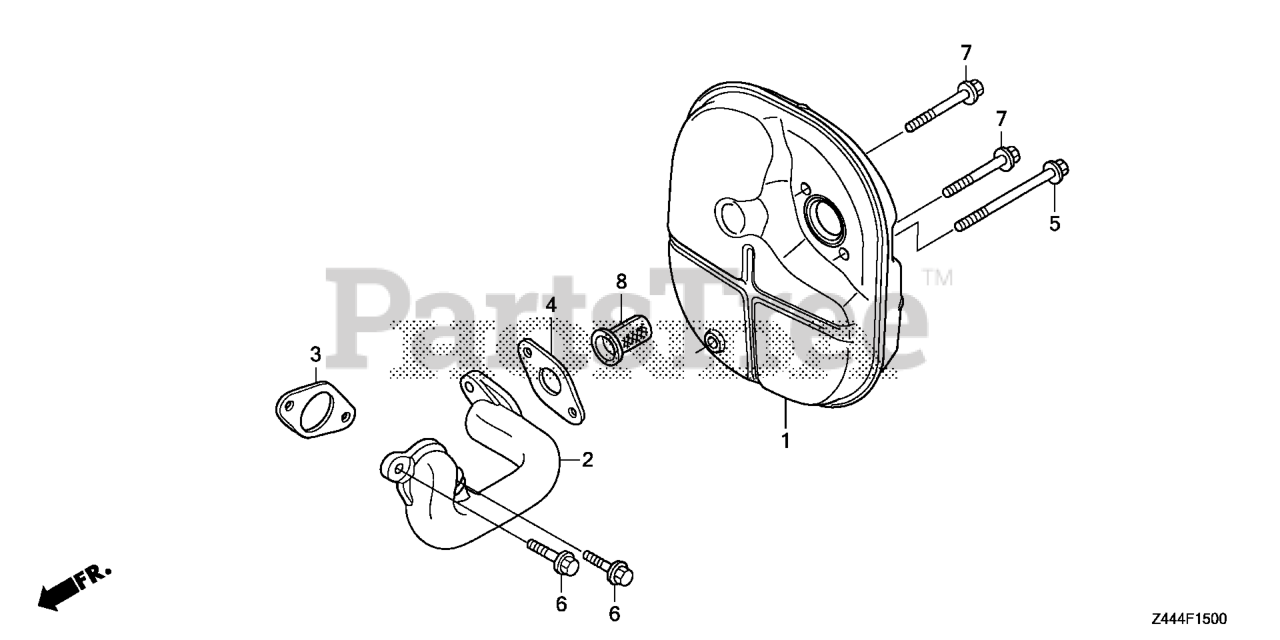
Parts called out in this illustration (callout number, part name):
3	GASKET, EX. PIPE
4	GASKET, MUFFLER
5	BOLT, FLANGE (6X65)
6	BOLT, FLANGE (6X23)
7	BOLT, FLANGE (6X45)
8	ARRESTER, SPARK
